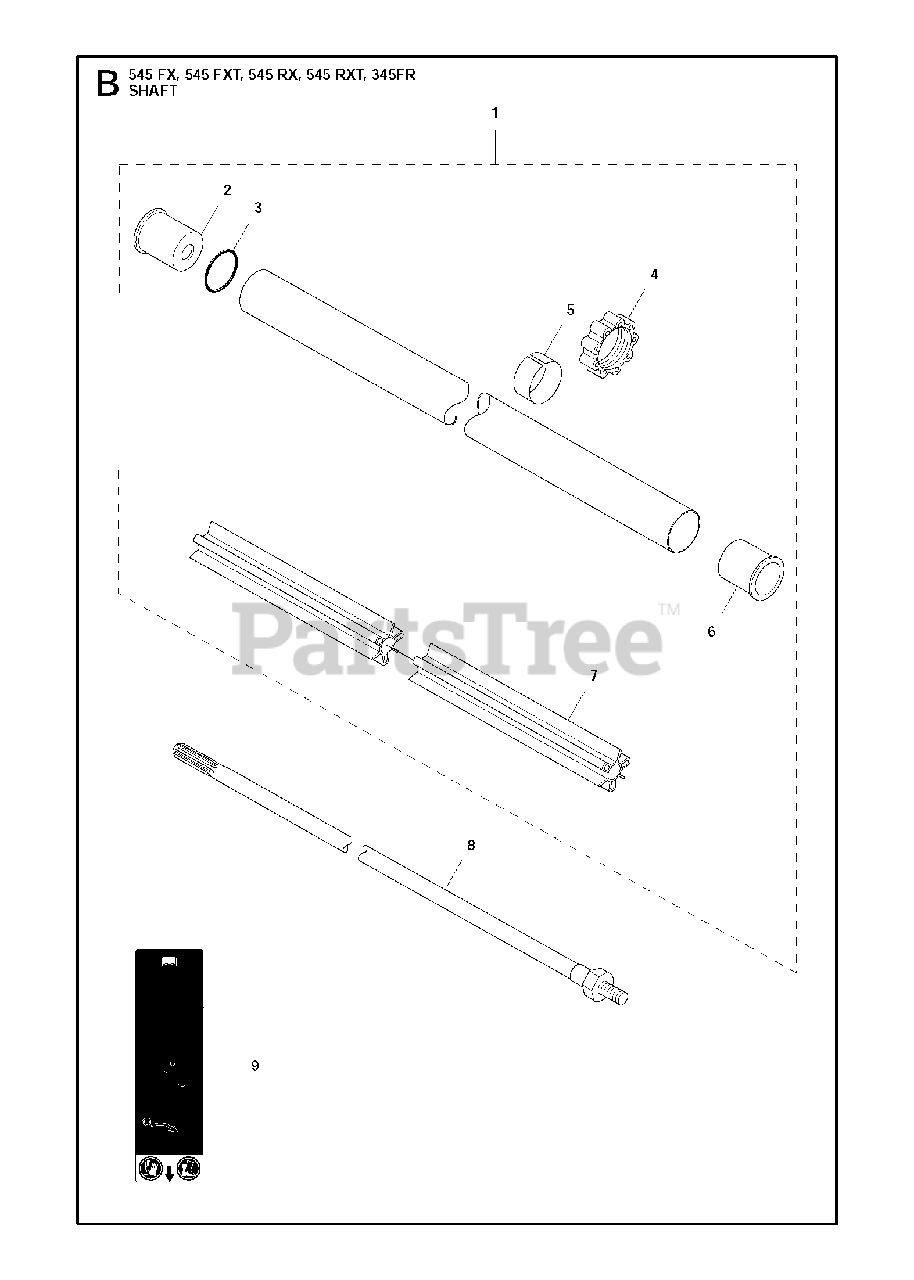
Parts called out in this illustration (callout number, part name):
1	TUBE ASSY
2	SPACER SLEEVE
3	O-RING
4	MOVEMENT LIMITER
5	%BAND
6	SPACER SLEEVE
7	BEARING SHAFT
8	SHAFT
9	LABEL WARNING TRIMMERS AND BRU
